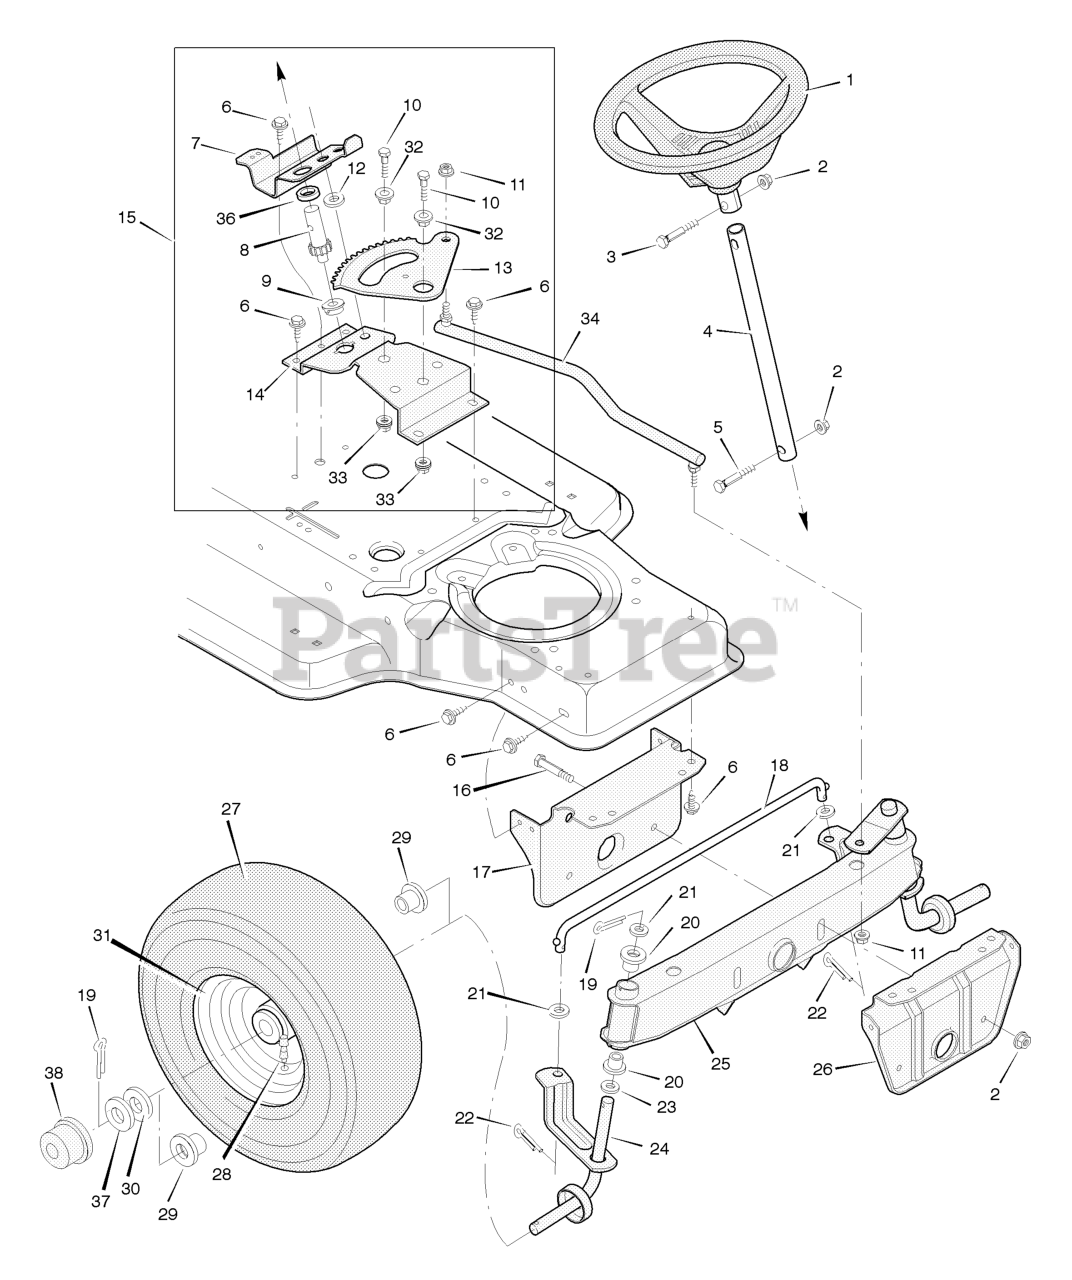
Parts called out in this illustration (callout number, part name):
1	Wheel, Steering
2	Nut, Hex
3	Bolt, Hex
4	Post, Steering
5	Bolt, Hex
7	Bracket, Sector
8	Gear, Pinion
9	Bearing
10	CAPSCREW, Hex Head, 5/16-18 x 1
11	Locknut, Flange
13	Gear, Sector
14	Bracket, Sector
15	Kit, Steering Gear
16	Bolt, Hex
17	Support, Rear Axle
19	Pin, Cotter
20	Bearing
22	Pin, Cotter
24	Spindle Assembly, Right
25	Spindle Assembly, Axle & Left
26	Support, Front Axle
28	Stem, Valve
29	Bearing, Wheel
31	Wheel & Tire Assembly
32	Bearing
33	Locknut, Flange
34	Link, Drag
36	Spacer, Pinion Gear
38	Hub Cap
